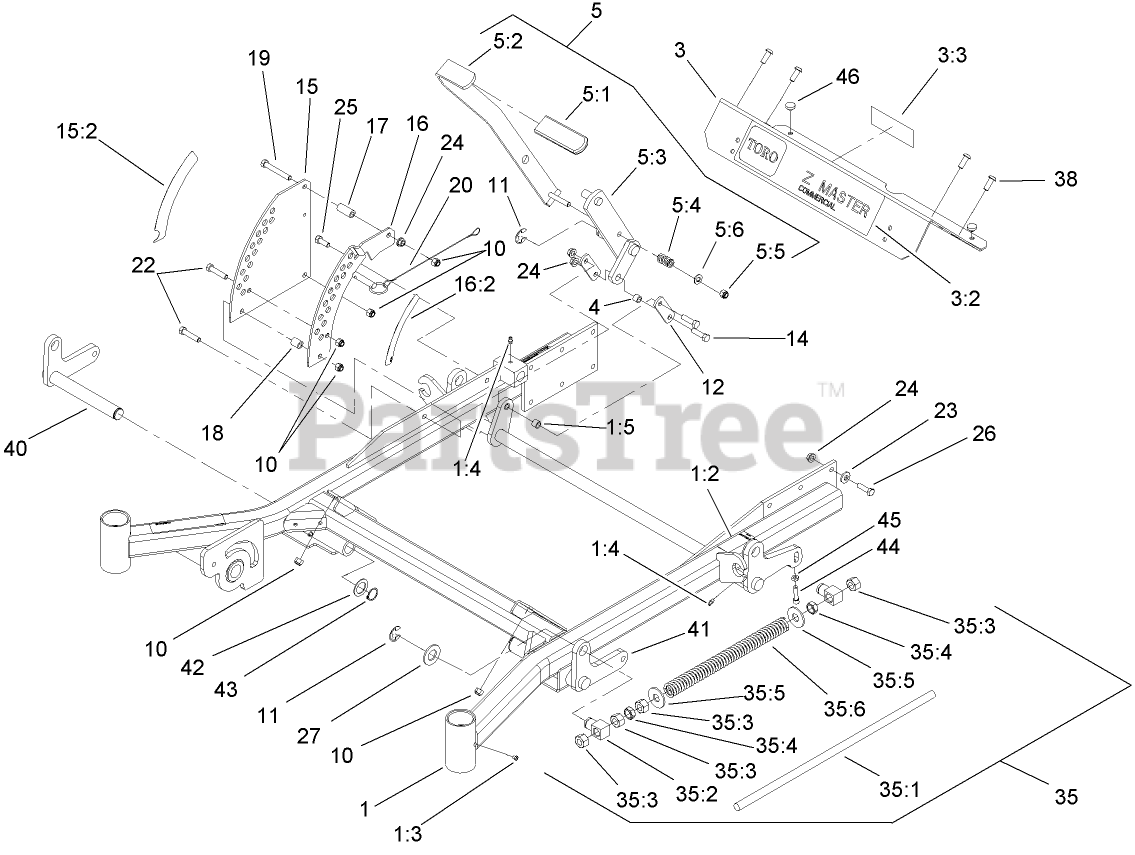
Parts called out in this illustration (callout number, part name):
1	FRAME ASM
1:2	Decal-Brake, Parking
1:4	FITTING-GREASE
1:5	Bushing
3	FOOTREST
3:3	DECAL-WARNING
4	Bushing
5	DECK LIFT HANDLE ASM
5:1	GRIP-LEVER, LIFT
5:2	LEVER-LIFT
5:3	ARM-LIFT, DECK
5:4	SPRING-COMPRESSION
5:5	NUT-LOCK, NI
5:6	WASHER-FLAT
10	NUT-LOCK, NI
11	RING-RETAINING, EXT
12	ARM-LIFT, DECK
14	SCREW-HH
15	PLATE-DECK LIFT, OUTER
15:2	Decal-Height, Deck
16	PLATE-DECK LIFT, INNER
16:2	Decal-Height, Deck
17	BUSHING-LEVER, LIFT
18	BUSHING-LEVER, LIFT
19	SCREW-HH
20	Hitch Pin ASM
22	SCREW-HH
23	WASHER-BELLEVILLE
24	NUT-HHF, WHIZ
25	SCREW-HH
26	SCREW-HH
27	WASHER-FLAT
35	Front Frame Spring ASM
35:1	ROD-LIFT, DECK
35:2	SWIVEL-DECK MOUNT, REAR
35:3	NUT-HEX
35:4	NUT-JAM
35:5	WASHER-FLAT
35:6	SPRING-SUPPORT, DECK
38	SCREW-HSBH
40	RH DECK LIFT ASM
41	LIFT-DECK, LH
42	WASHER-SPACER
43	RING-RETAINING
44	SCREW-HSH
45	NUT-JAM
46	BUMPER
